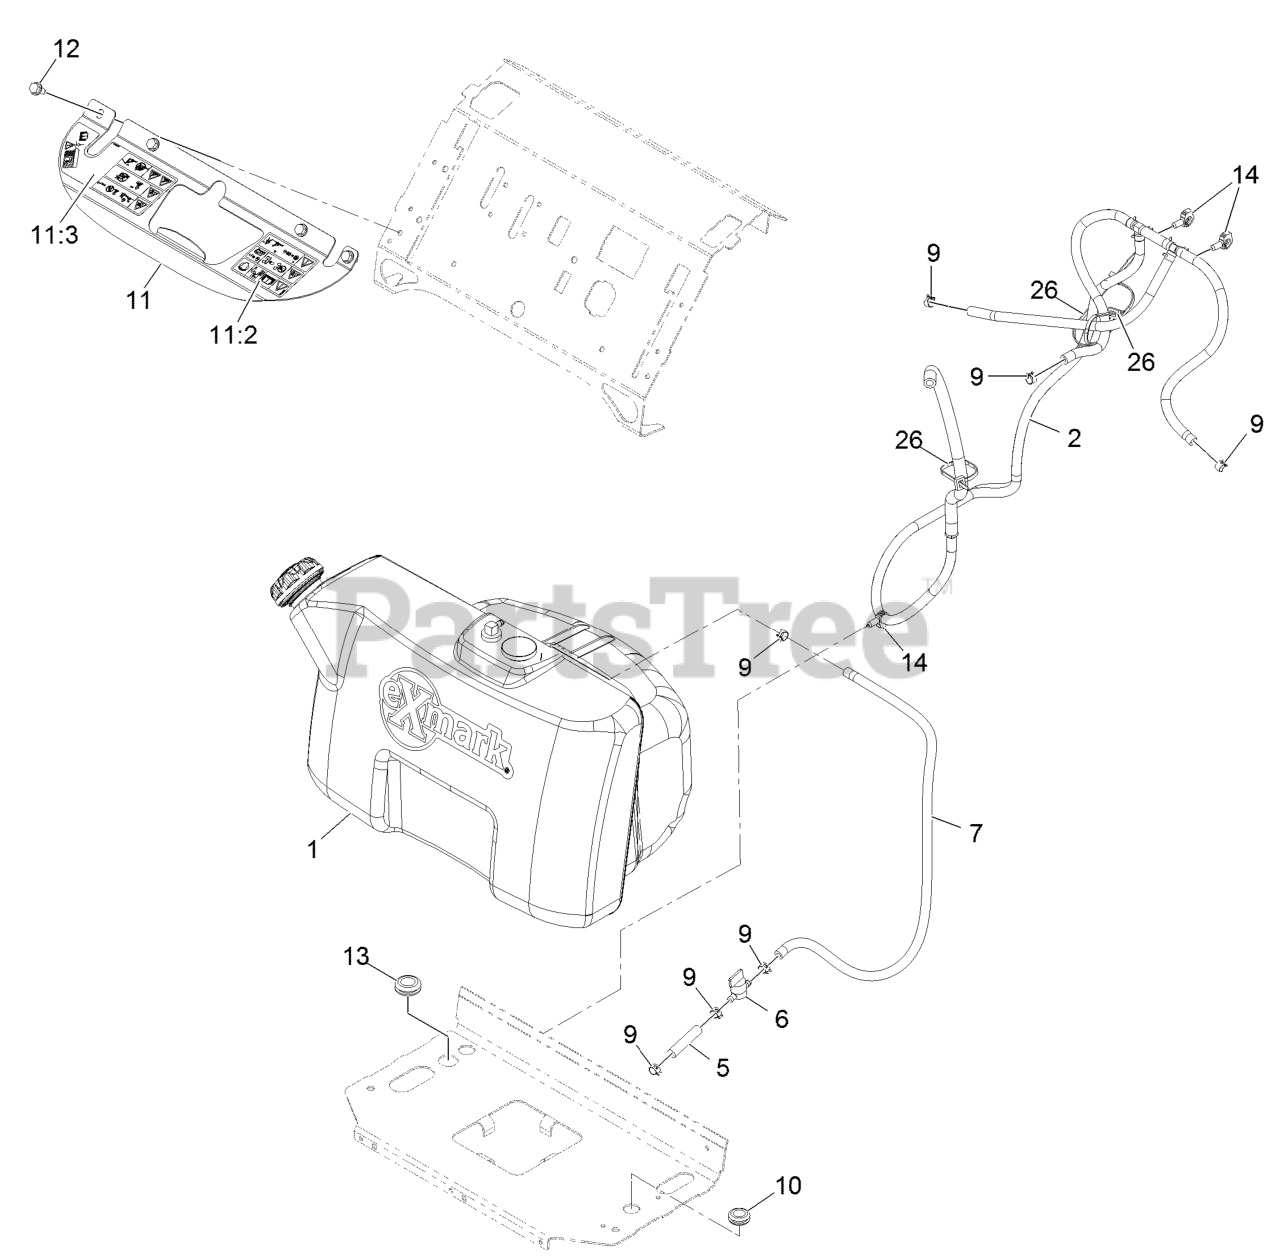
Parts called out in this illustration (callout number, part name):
2	VENT ASM
5	HOSE-FUEL
6	VALVE-FUEL
7	HOSE-FUEL
9	CLAMP-HOSE
10	GROMMET
11	BRACKET-TANK
11:2	DECAL-WARNING LH
11:3	DECAL-WARNING RH
12	Screw-HWH 5/16-18 X 3/4 Tf
13	GROMMET
14	CLIP-HARNESS
26	TIE-CABLE
